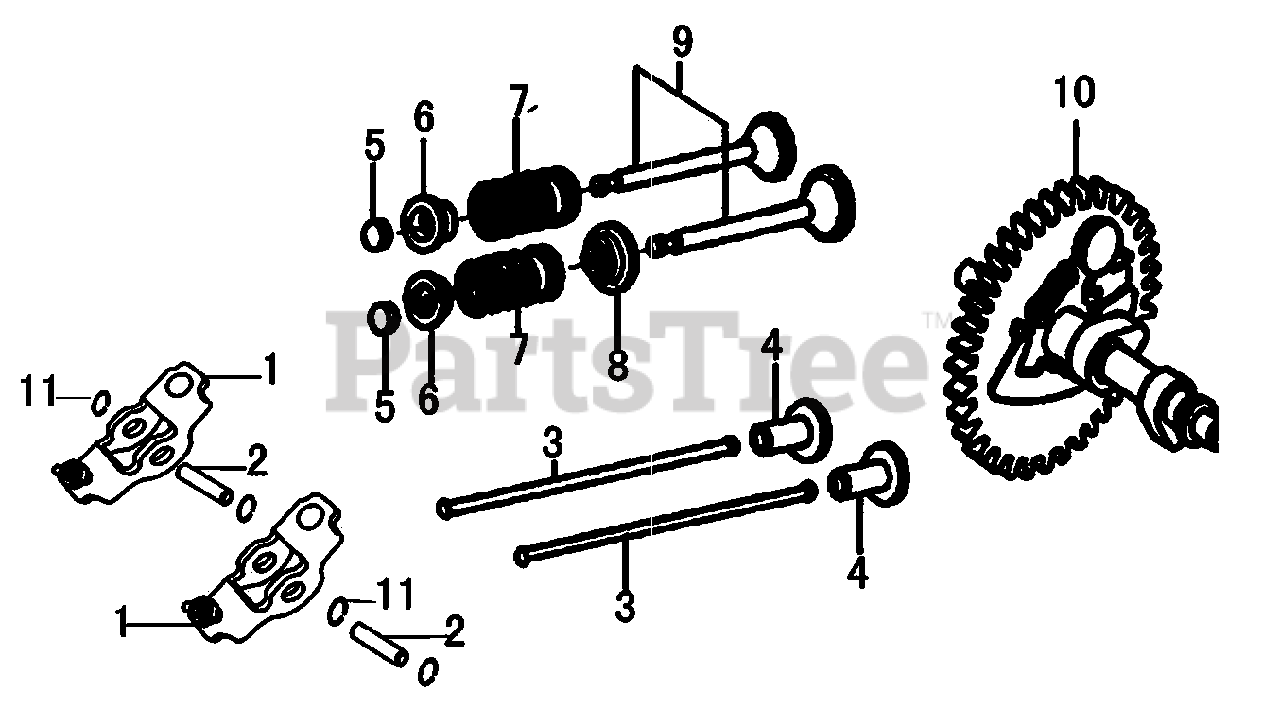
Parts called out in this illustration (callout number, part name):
1	ROCKER ARM
2	VALVE ROCKER SHAFT
3	ROD, PUSH
4	LIFTER VALVE
5	ROTATOR, VALVE
6	RETAINER, VALVE SPRING
7	SPRING , VALVE
8	SEAL, GUIDE
9	VALVES,INTAKE&EXHAUST SET OF 2
10	CAMSHAFT ASSY.
11	SPLIT WASHER
